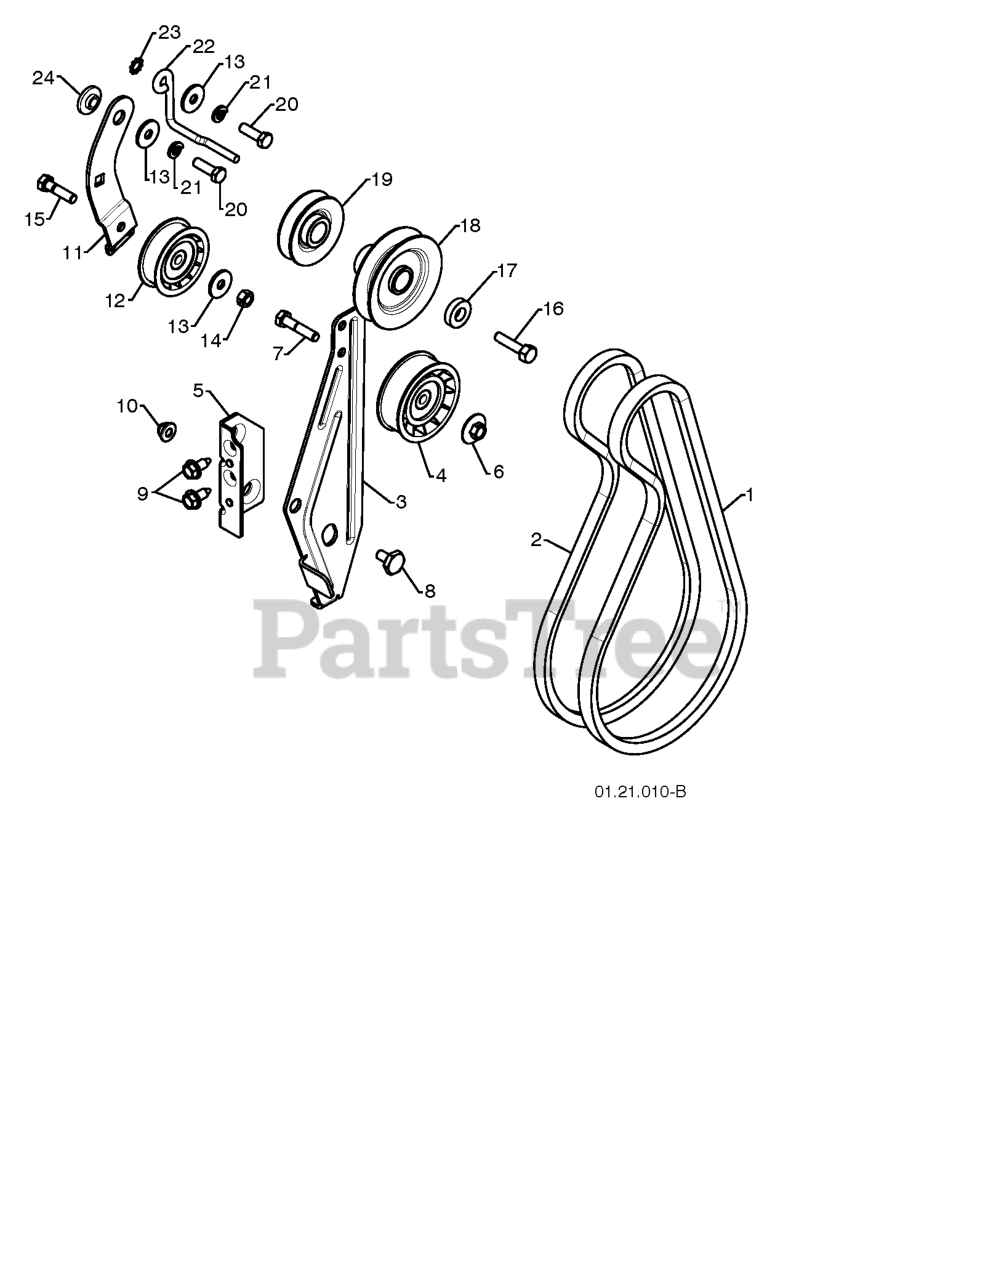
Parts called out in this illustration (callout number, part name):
1	VBELT; IMPELLER_39.09
2	V-BELT.TRACTION.HYDRO
3	ARM.IDLER.BRAKE.
4	PULLEY.W/SPACER.2.75
5	RP BRACKET.IDLER.PIVOT
6	NUT.FLANGE.HEX.5/16X18.BLACK
7	HEX BOLT
8	BOLT.SHOULDER.1/2X12
9	BOLT.HEX.HD.WASHER.5/16-18X.75
10	NUT.LOCK.5/16-18
11	ARM, IDLER
12	PULLEY.W/SPACER.2.25
13	STEEL WASHER
14	NUT.71038.31-18.HEX.NYLOCK
15	BOLT.5/16-18X1-1/4 FULL.THREAD
16	SCREW, HEX HD 3/8-24 X 1-3/8
17	WASHER, FLAT 3/8
18	PULLEY.ENG.IMPELLER.SNOW
19	PULLEY,ENGINE TRACTION DRIVE
21	WASHER.LOCK.HVY.HLCL.SPR.5/16
22	GUIDE, BELT
23	WASHER EXT TOOTH LOCK 5/16
24	RP BUSHING, IDLER PIVOT
